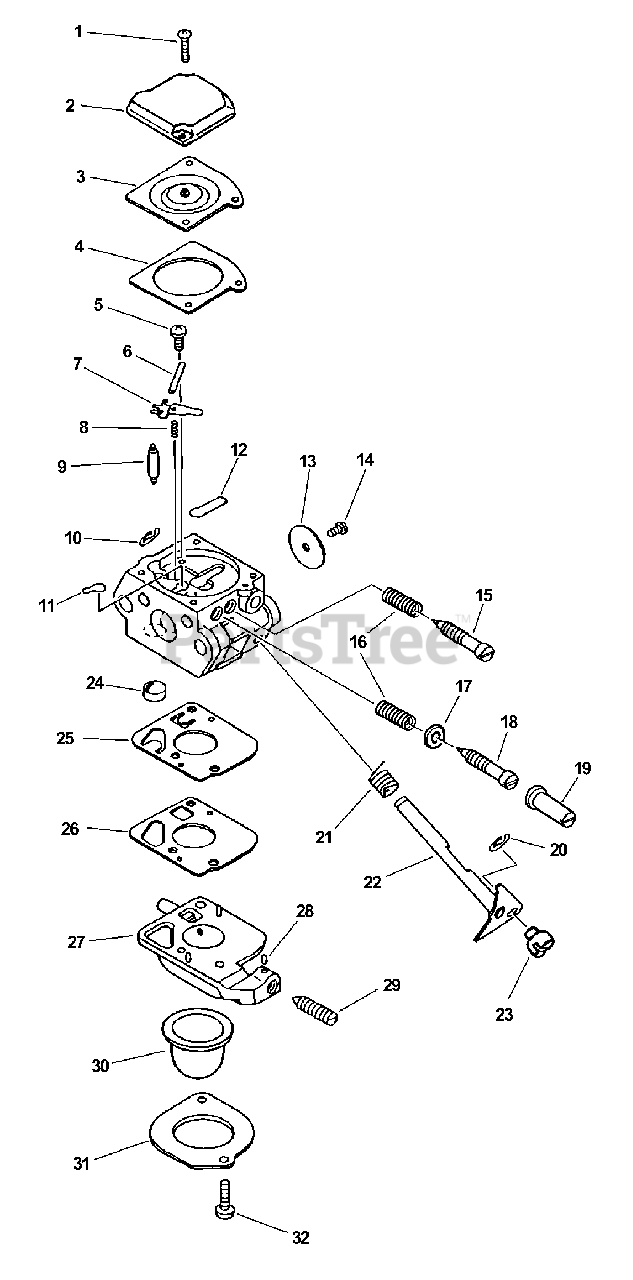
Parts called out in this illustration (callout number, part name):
2	COVER, METERING
3	DIAPHRAGM
4	GASKET, METERING
5	SCREW, METERING LEVER PIN
6	PIN, METERING LEVER
7	LEVER, METERING
8	SPRING, INLET NEEDLE
9	VALVE, NEEDLE
10	RING, RETAINING
11	PLUG, WELCH
12	PLUG, WELCH
13	VALVE, THROTTLE
15	NEEDLE - LOW SPEED
18	NEEDLE - HIGH SPEED
19	CAP, LIMITER
20	RING, RETAINING
21	SPRING, RETURN
22	SHAFT, THROTTLE
24	STRAINER
25	DIAPHRAGM, PURGE
26	GASKET, PURGE
27	BASE, PURGE
28	PIECE, FRICTION
29	SCREW, IDLE ADJUST
30	BULB, PURGE
31	RETAINER, PURGE BULB
32	SCREW, RETAINER
32	REPAIR KIT
32	DIAPHRAGM/GASKET KIT
